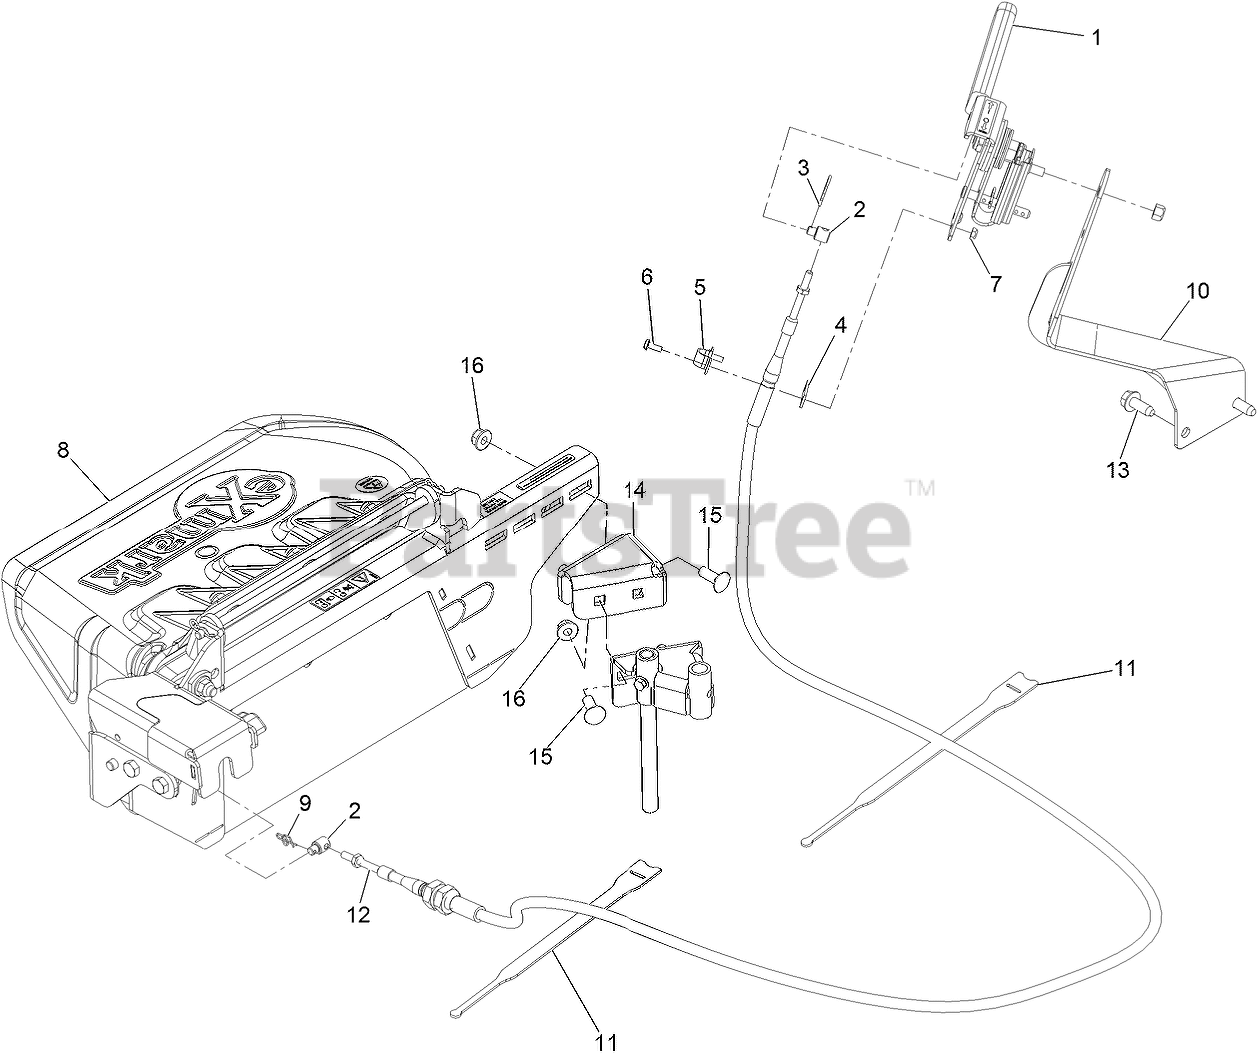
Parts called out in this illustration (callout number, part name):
1	ASM, HAND LEVER
2	PIVOT, CONTROL CABLE
3	PIN-COTTER
4	SHIM,CONTROL CABLE
6	SCREW-PPH
7	NUT-LOCK, NI
8	ASM, OCD
9	PIN-COTTER, LOCKING
10	Mount-Handle Ocdc
11	STRAP-VELCRO, CABLE TIE
12	CABLE-DISCHARGE GATE
13	SCREW-FORMING, THREAD
14	BRACKET-OCD
15	SCREW-CARR
16	NUT-HF, NI
